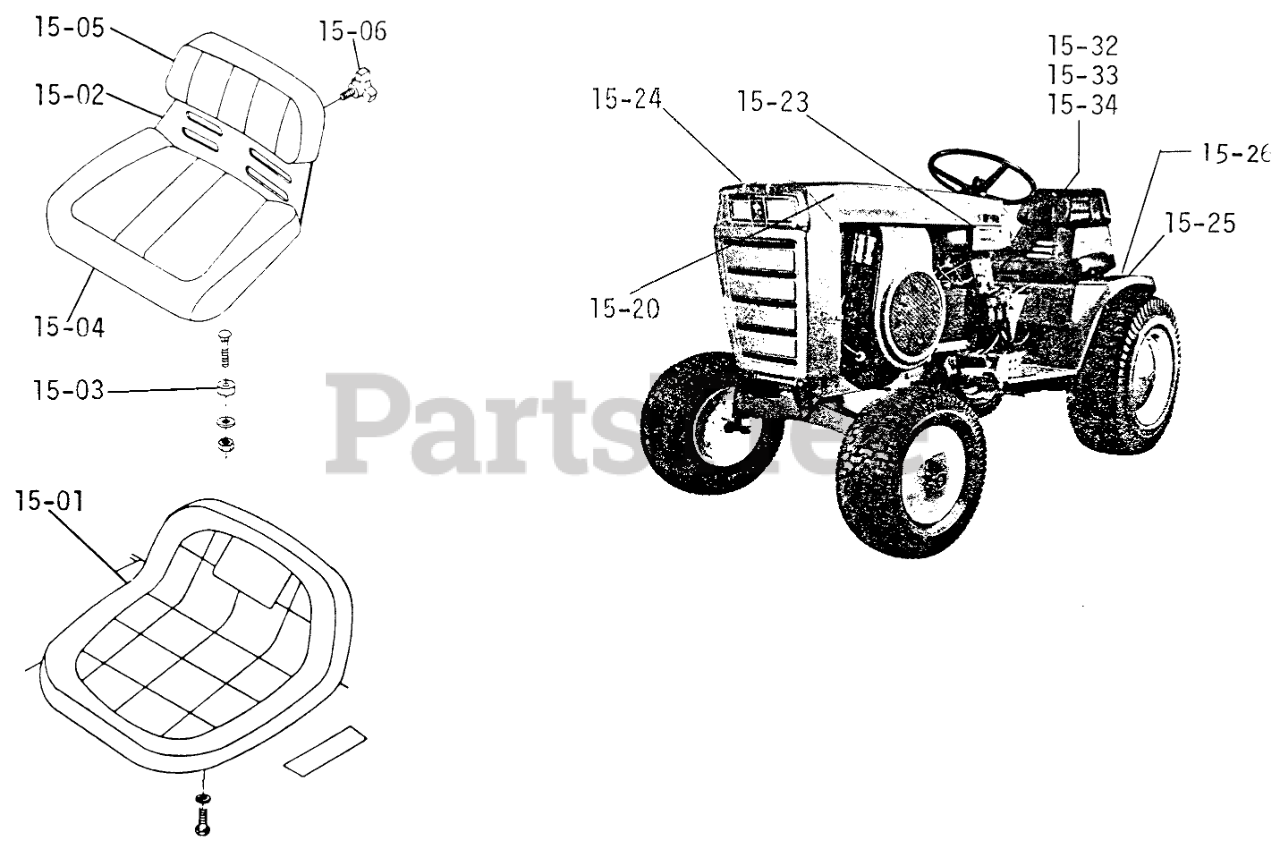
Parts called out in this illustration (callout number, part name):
15-01	Seat
15-02	Seat Base
15-03	Spacer
15-04	Cushion Seat
15-05	Back Cushion
15-06	Knob 8 HP
15-20	Decal-Hood
15-23	Decal-Charge 10 (C10)
15-24	Decal-Racing Stripes
15-25	Decal
15-26	Reflector
15-36	Decal
15-37	Decal Free Wheeling
15-38	Decal
